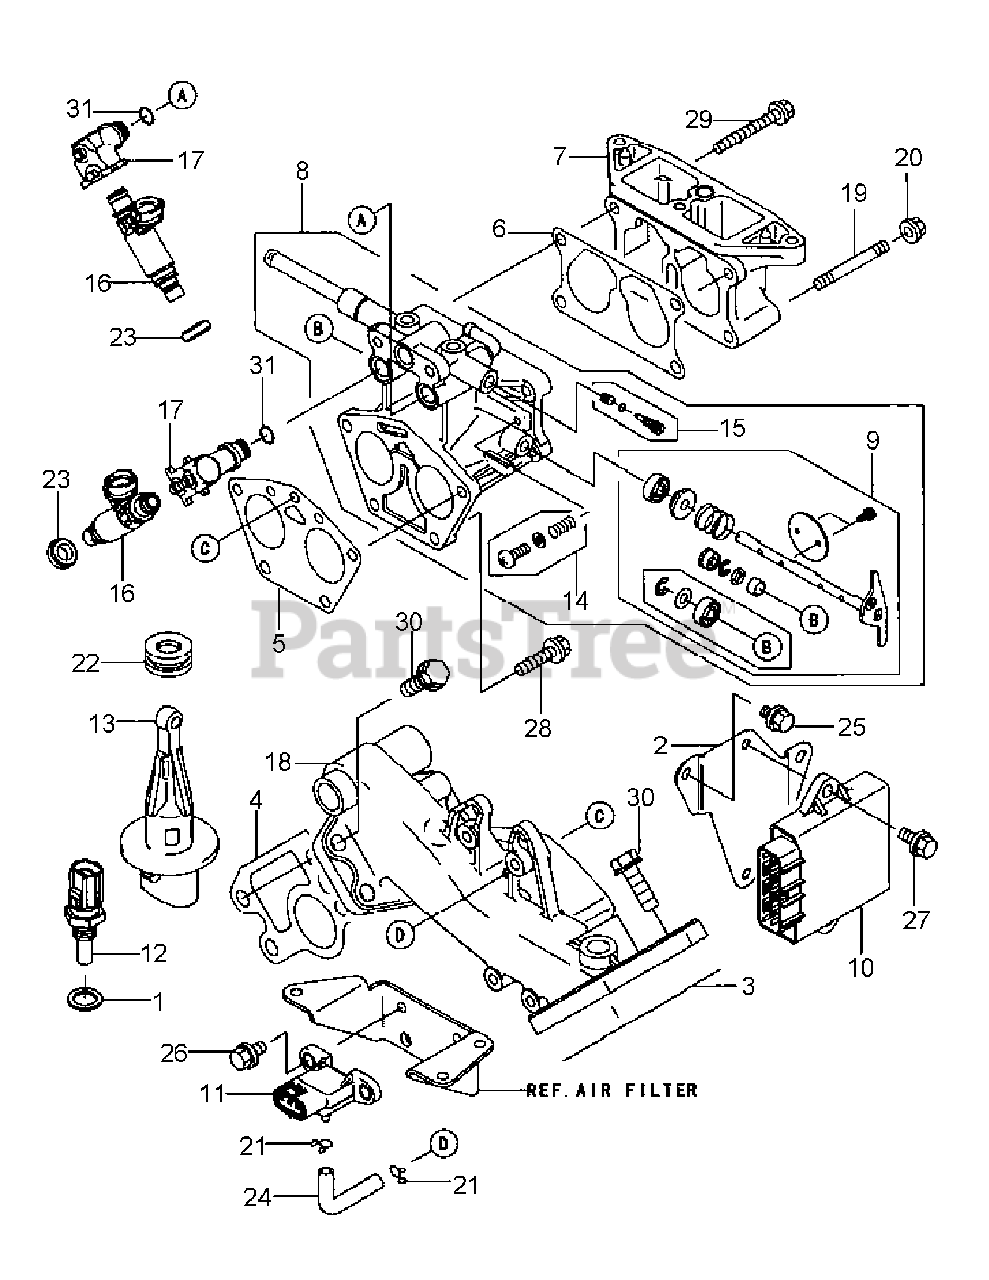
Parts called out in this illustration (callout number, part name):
3	INTAKE MANIFOLD GASKET
4	INTAKE MANIFOLD GASKET
5	THROTTLE GASKET
6	INTAKE PIPE GASKET
8	THROTTLE ASSY.
9	THROTTLE VALVE ASSY.
10	ELECTRONIC CONTROL UNIT
16	INJECTION NOZZLE
17	INJECTION PIPE
18	INTAKE MANIFOLD
25	FLANGED BOLT
26	FLANGED BOLT
27	FLANGED BOLT
28	FLANGED BOLT
29	FLANGED BOLT
30	FLANGED BOLT
31	O-RING, 8mm
